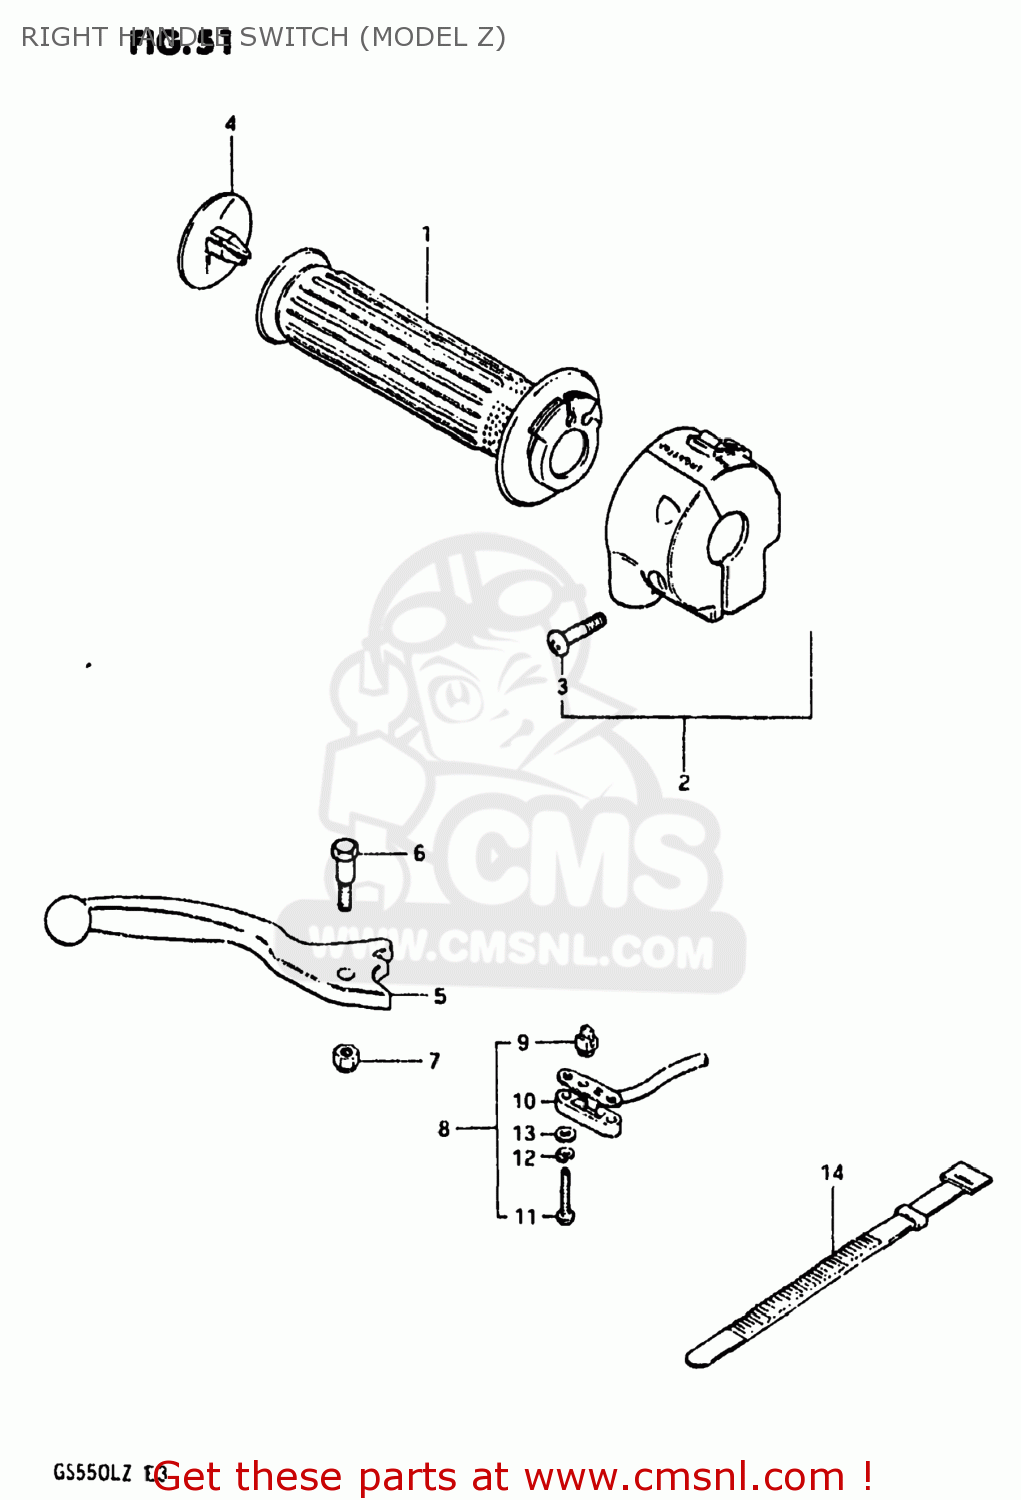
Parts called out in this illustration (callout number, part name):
1	GRIP,THROTTLE
2	SWITCH ASSEMBLY,HANDLE,RIGHT
3	SCREW
4	CAP,GRIP END
5	LEVER,BRAKE
6	BOLT
7	NUT 6MM
8	SWITCH ASSEMBLY
9	CONTACT,SWITCH
10	COVER,FR BK TERMINAL BASE
11	SCREW
12	LOCK WASHER
13	WASHER
14	CLAMP(L:120)
